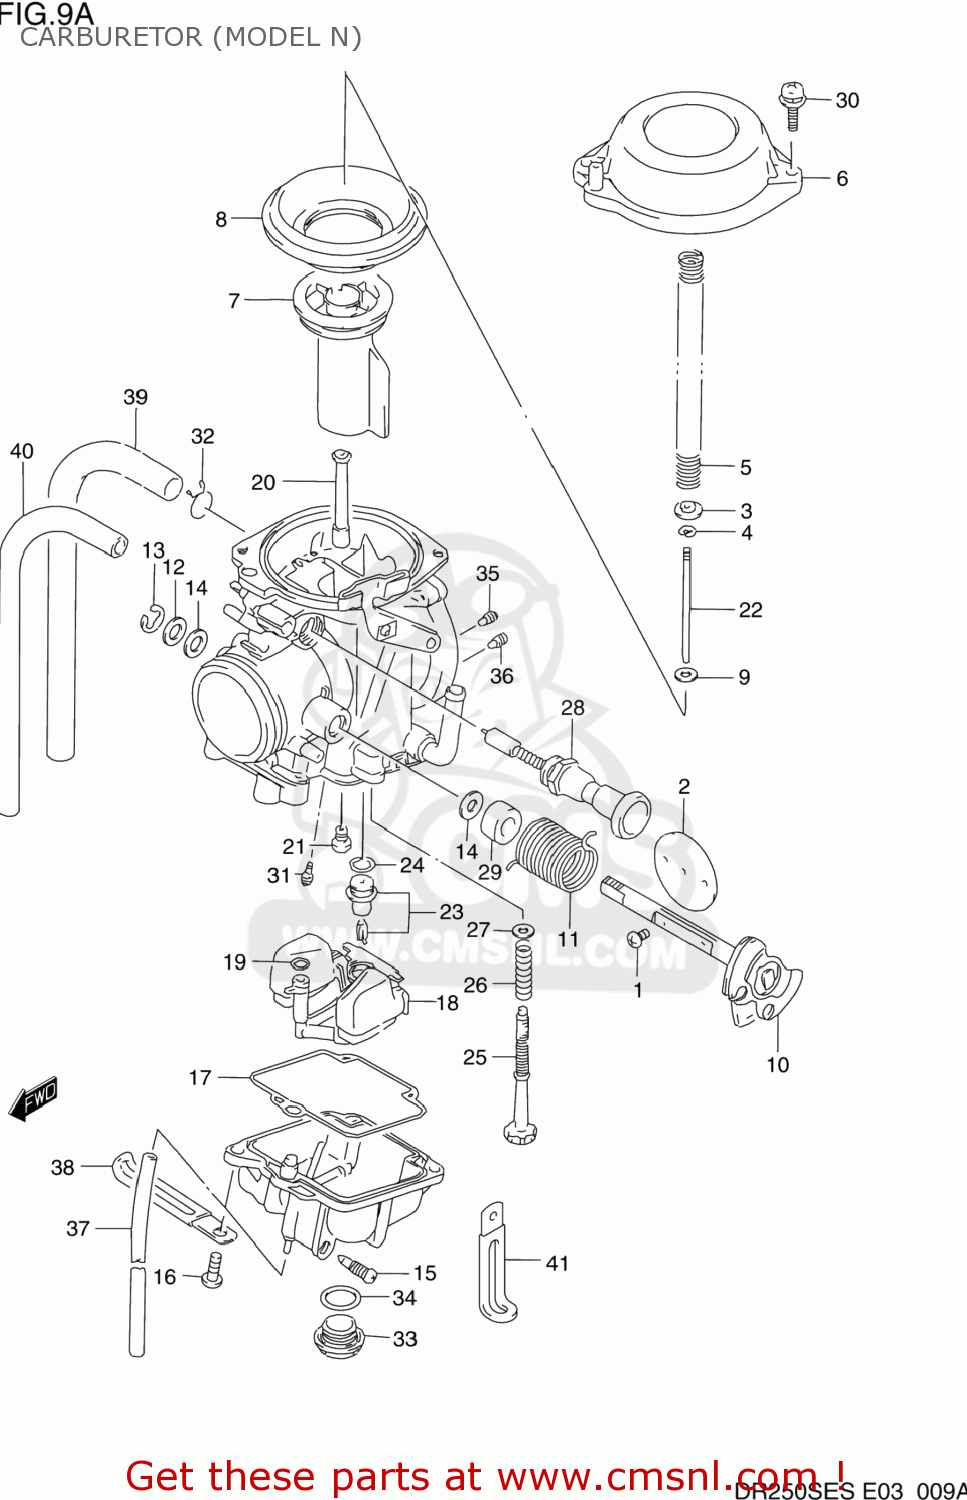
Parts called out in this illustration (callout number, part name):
1	SCREW
2	VALVE,THROTTLE (115)
3	RING
4	E RING
5	SPRING
6	COVER,DIAPHRAGM
7	VALVE PISTON
8	DIAPHRAGM
9	RING
10	SHAFT ASSEMBLY
11	SPRING
12	GASKET,THROTTLE SHAFT (NAS)
13	E RING
14	SEAL
15	SCREW,DRAIN
16	SCREW
17	GASKET,FLOAT CHAMBER (NAS)
18	FLOAT ASSY
19	O RING
20	JET,NEEDLE (O-6)
21	JET,MAIN(132.5)
22	NEEDLE,JET
23	VALVE ASSEMBLY,NEEDLE
24	O-RING,NEEDLE VALVE
25	SCREW,ADJUSTER
26	SPRING
27	WASHER
28	PLUNGER ASSEMBLY
29	RING
30	SCREW
31	JET(40)
32	CLIP
33	SCREW,GUIDE
34	O RING,DRAIN PLUG
35	JET,AIR
36	JET,AIR(0.6)
37	HOSE
38	CLIP
39	HOSE
40	HOSE
41	CLAMP L:35
